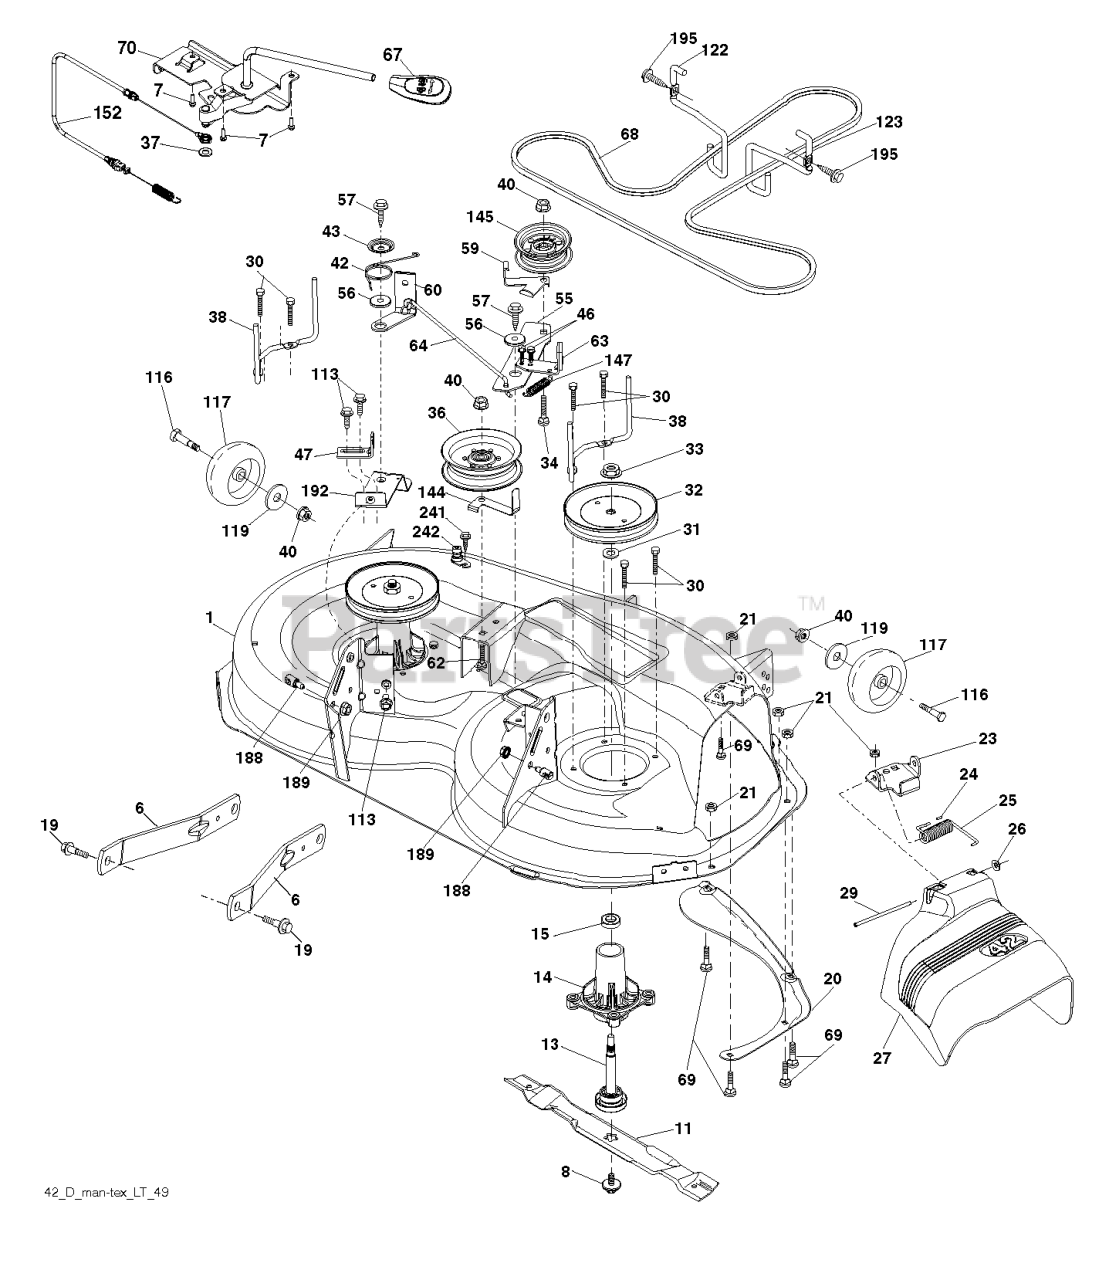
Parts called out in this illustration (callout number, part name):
1	DECK.WELDMENT.42"
6	ARM.SUSPENSION.MOWER.R
7	SCREW.#10 X 0.750.BOS
8	BOLT.WASHER.ASM.7/16-2
11	42" HI-LIFT BLADE
13	SHAFT.ASM.MDRL.N/GREASE.38
14	RP.HOUSING.MANDREL.4PT.
19	BOLT.SHOULDER
20	BAFFLE.VORTEX
21	LOCKNUT
23	BRKT.DEFLECTOR.38"2005+
24	CAP-SLEEVE LT
25	SPRING.TORSION.DEFLECT
26	NUT PUSH M
27	SHIELD.DEFLECTOR.MOWER.42"BLAC
29	ROD.HINGE
30	SCREW, WASHER HEAD
31	WASHER.SPACER.MANDREL
32	PULLEY.MANDREL.5.438.PD
33	NUT.FLANGE.LOCK.TOP
34	BOLT.3/8-16X1.50
36	PULLEY.IDLER.2006
37	WASHER
38	KEEPER.BELT.LH.MANDREL
40	NUT LOCK FLG 3/8-16 UNC
42	SPRING.TORSION.BRAKE
43	SRPING.TORSION.RETAINE
46	SCREW.1/4-20X5/8
47	BRKT.CLUTCH.CABLE
55	IDLER.ARM.42"
56	SPACER.RETAINER
57	SCREW 3/8-16X1
59	GUARD, BELT
60	ARM BRAKE MOWER
63	ARM BRAKE MOWER
64	LINK BRAKE
67	HANDLE.CLUTCH.CABLE.LT
68	BELT.DECK.DRIVE.42"
69	BOLT
70	CLUTCH.ASM.MANUAL.LT.PRED
113	BOLT.5/16HEX.WHS.HD
116	BOLT M
117	WHEEL.GAGE.HALF.SPOKED
119	WASHER.5/16.FLAT.STE.STD.
122	KEEPER BELT ENGINE LH
123	KEEPER BELT RH
144	KEEPER.BELT.MOWER
145	PULLEY.IDLER.48"PRIMARY
147	RETURN SPRING
152	CLUTCH CABLE
188	STUD.FASTNER.W/ANTI-ROTATE
189	NUT LOCK HEX FLANGE 5/16-18
192	BRKT.BRAKE.STAND.LH.
195	SCREW, 3/8-16X3/4
241	SCREW.TT.#10-32X.5.3/8.FLANGE
242	PORT.WASHOUT
